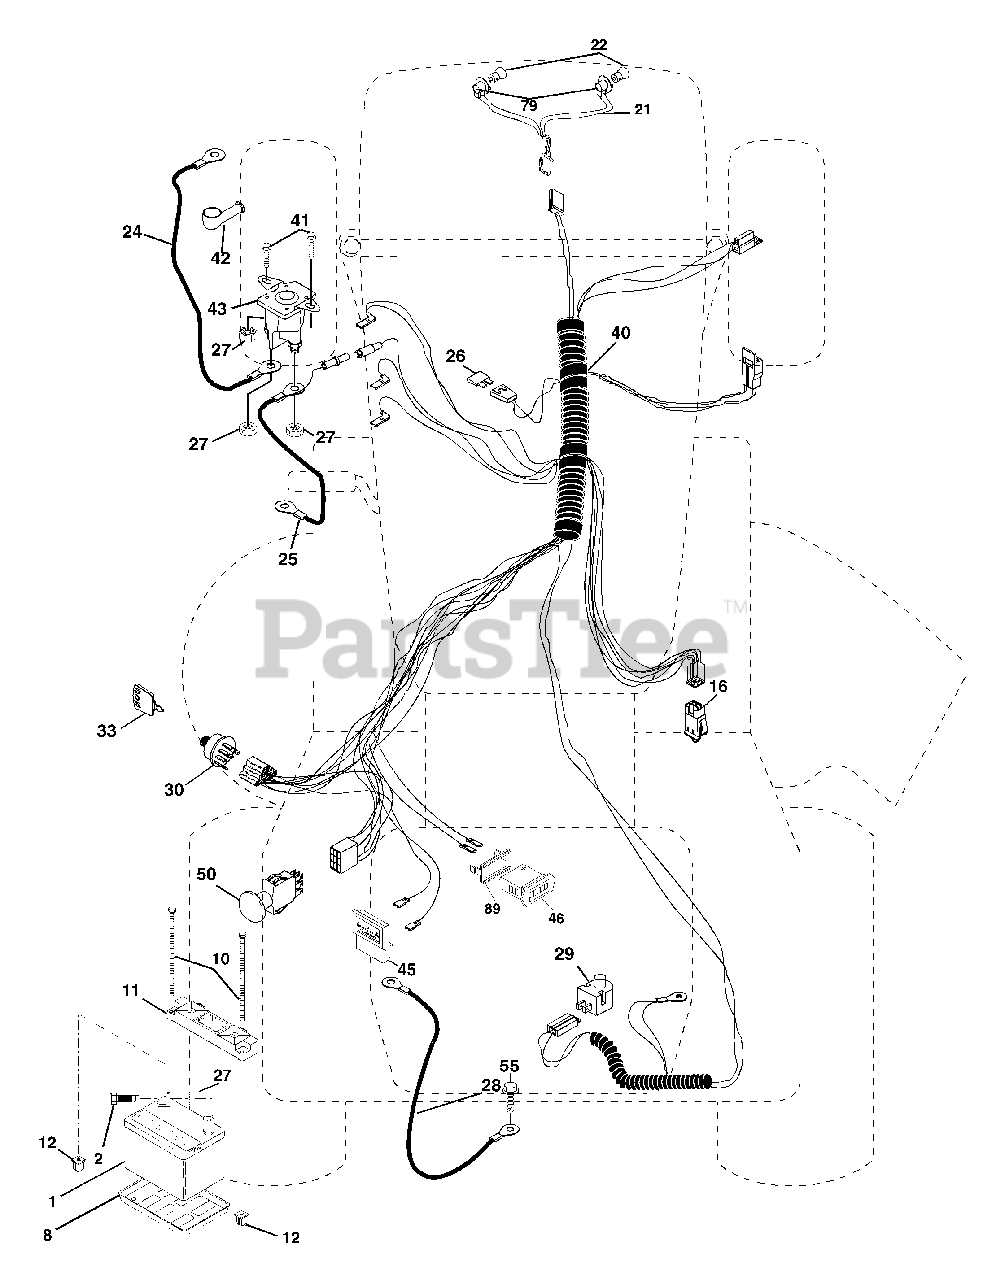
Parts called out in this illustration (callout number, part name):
1	Battery
2	Bolt Hex Hd 1/4-20 unc x 3/4
8	Tray, Battery
10	Bolt, BTR FRT 1/4-20 x 7.5
11	Hold Down Battery, Front
12	Nut, Push, Nylon
16	Switch Interlock Push-In
21	Harness Asm Light W/Bulbs
22	Bulb Light
24	Cable Battery
25	Cable Batterywire
26	Fuse
27	Nut Keps Hex 1/4-20 unc
28	Cable Ground
29	Switch Plunger Normal NC Gray
30	Switch Ign 4 pos w/lights
33	Key Ign
40	Harness Ign.
41	Bolt Blk Fin Hex 1/4-20 x 1/2
42	Cover Terminal Red
43	Solenoid
45	Ammeter Rectangular
46	Hourmeter Snap-In
50	Switch, PTO
55	Screw Thdrol 5/16-18 x 1/2
79	Bulbholder
89	Bracket Snap-In Hourmeter
